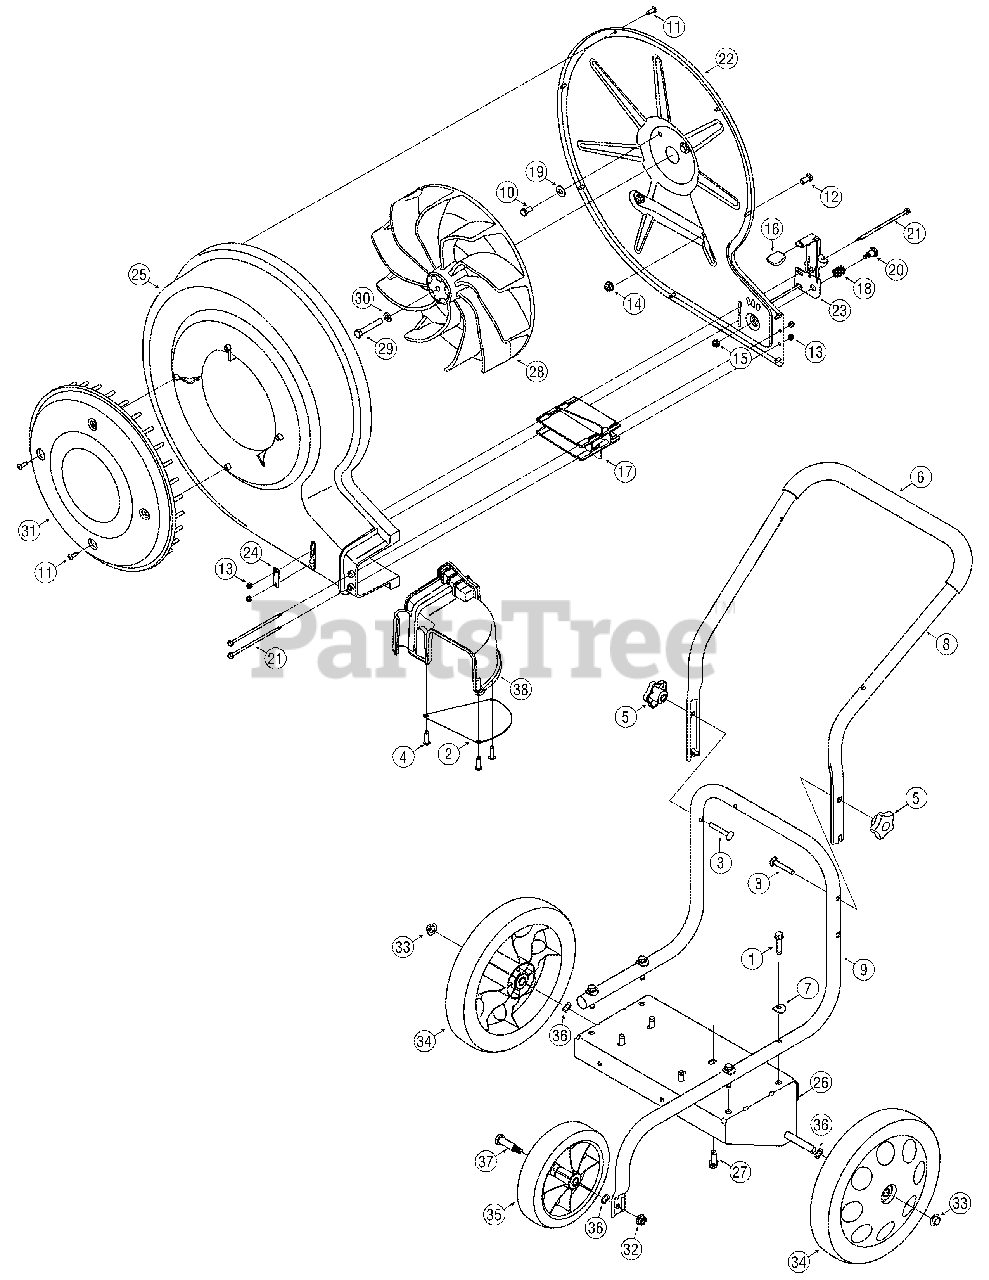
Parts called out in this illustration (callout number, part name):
1	TT Screw, 5/16-18 x 1.50
3	Carriage Screw, 5/16-18 x 2.00
4	Screw, #12-16 x .750
5	Star Knob
7	Saddle Washer, .320 x .93 x .060
10	Screw, 5/16-24 x .625
11	Screw, #12-16 x .750
12	Screw, 5/16-18 x .75
13	Hexlock Nut, #8-32
14	Flange Lock Nut, 5/16-18
15	Flange Lock Nut, 1/4-20
16	Knob
17	Louver Plate
18	Compr. Sprng., .515 x .641 x .95
19	Bell Washer, .340 x .872 x .060
20	Shoulder Scr., .437 x .13, 1/4-20
21	Shoulder Scr., .18 x 4.8, 8-32
25	Blower Housing
27	TT Screw, 3/8-16 x 1.00
28	Impeller Assembly
29	Screw, 3/8-24 x 2.25
30	Washer, Lock, 3/8
31	Blower Cover
32	Flange Lock Nut, 3/8-16
34	Wheel, 12 x 2.125
35	Wheel, 8 x 2
36	Washer, Wave, .510 x .750 x .017
37	Shoulder Screw, .498 Dia. X 1.44
38	Chute Attachment
